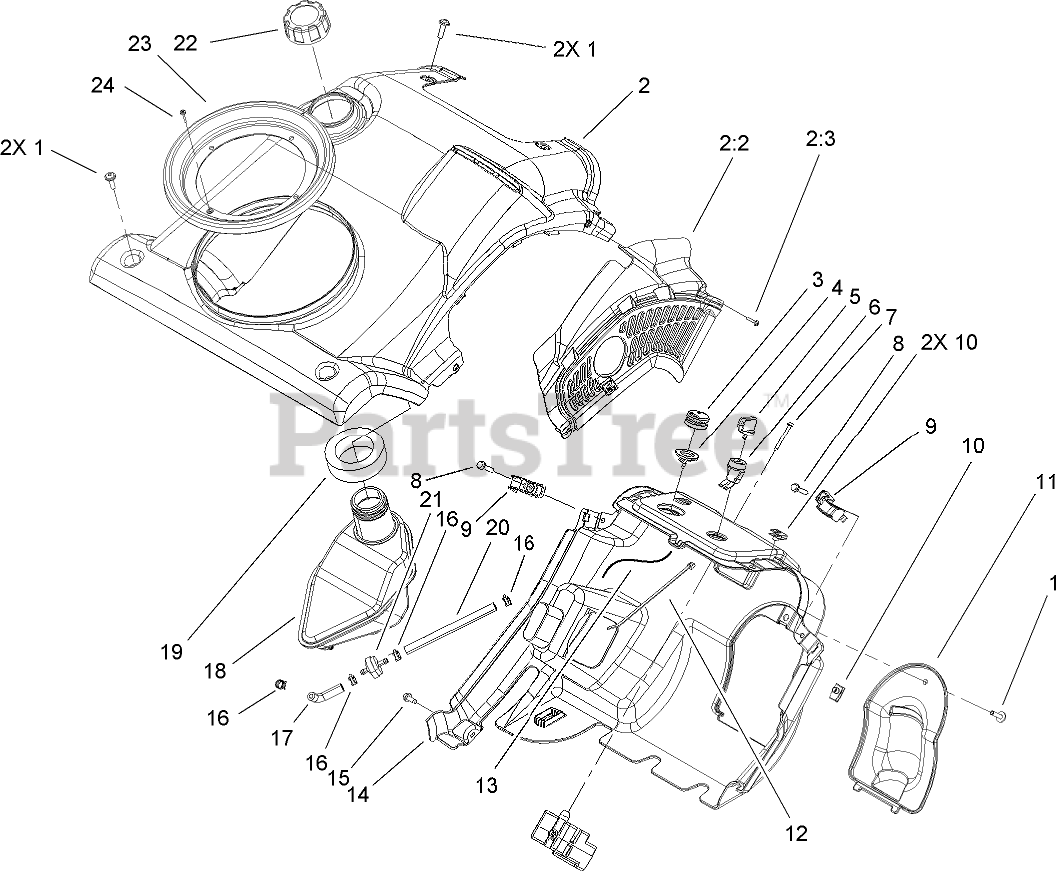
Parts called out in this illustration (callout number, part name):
1	SCREW-PPH
2	SHROUD ASM
2:2	BAFFLE-HEAT
2:3	SCREW-PPH
3	BULB-PRIMER
4	BODY-PRIMER
5	KEY-IGNITION
6	SWITCH
7	SCREW-PLASTITE
8	SCREW-PLASTITE
9	CLIP-SHROUD
11	PANEL-ACCESS, CARBURETOR
12	TIE-CABLE
13	HOSE-PRIMER
14	SHROUD-LOWER
15	SCREW-HWH
16	CLAMP-HOSE
17	HOSE-FUEL
18	TANK-GAS
19	SEAL-TANK
20	HOSE-FUEL
21	FILTER-FUEL
22	GAS CAP ASM
23	SEAL-RING, CHUTE
24	SCREW-PPH
